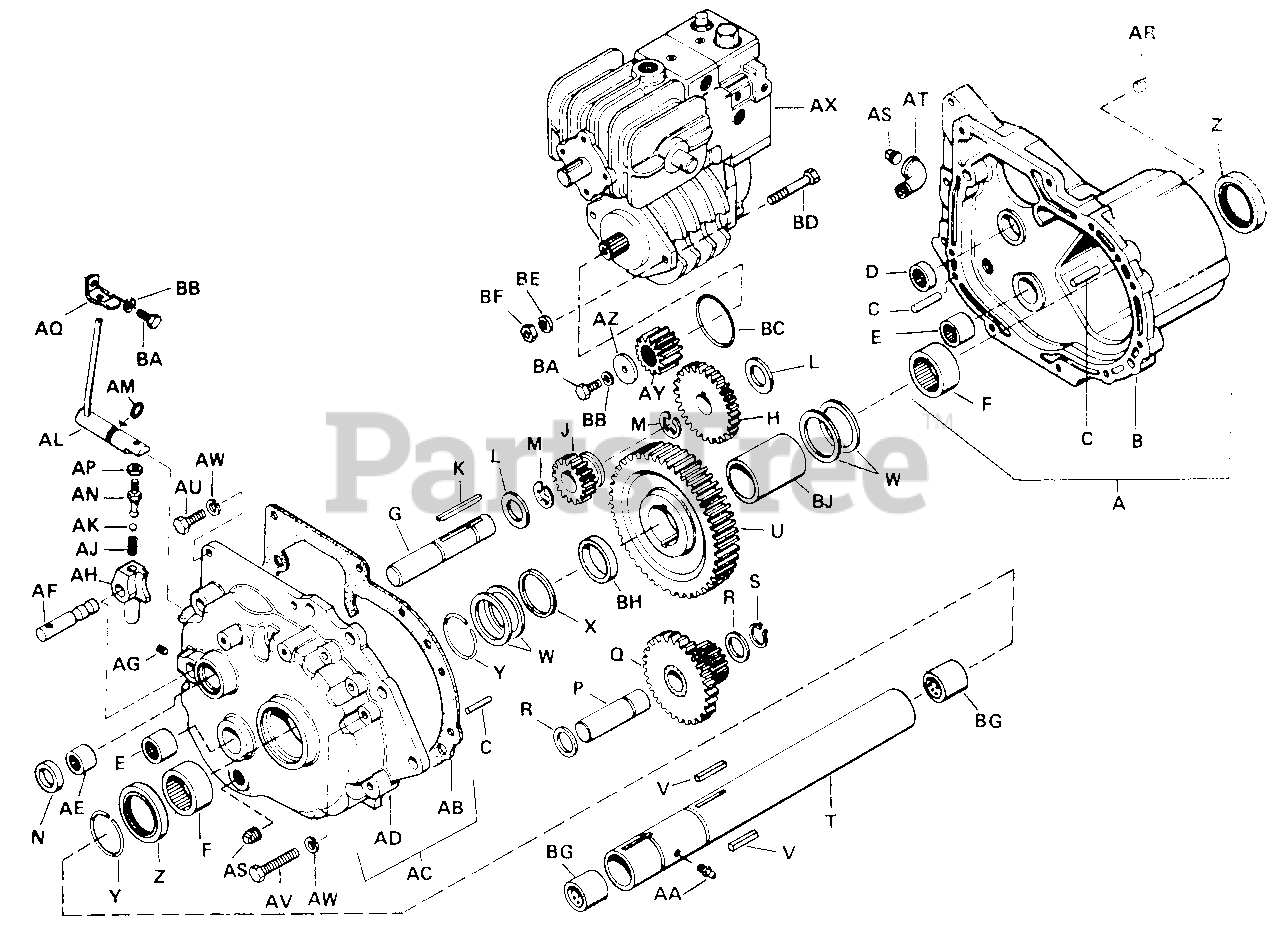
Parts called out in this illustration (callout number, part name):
A	Gear Case Complete (includes B thru F)
B	Gear Case
C	Roll Pin, 3/8 x 1-1/4"
D	Needle Bearing
E	Needle Bearing
F	Needle Bearing
G	Brake Shaft
H	Gear-1st Interm.
J	Sliding Pinion
M	Retainer Ring
P	Shaft, Interm.
Q	Pinion & Gear Assembly
S	Retaining Ring
T	Axle Tube Assembly
U	Drive Gear
AA	Grease Fitting
AB	Gear Case Gasket
AC	Gear Case Cover Sub. Assy. (includes AD, AE, E, F)
AD	Gear Case Cover
AE	Needle Bearing
AF	Shifter Shaft
AG	Cone Pt. Setscrew, Hollow Hd., 5/16"-18 x 1/2"
AH	Shift Fork
AK	Shift Lock Ball
AL	Shift. Shaft Assembly
AP	Hex. Jam Nut, 5/16"-24
AQ	Lift Lever Latch
AR	Pipe Plug, 1/4"
AS	Pipe Plug, 3/8"
AT	Street Elbow, 3/8"
AU	Hex. Capscrew, 5/16-18 x 1"
AV	Hex. Capscrew, 5/16-18 x 2"
AW	Lock Washer, 5/16"
AX	Hydrostatic Pump & Motor Unit
AY	Motor Shaft Pinion
BA	Hex. Capscrew, 5/16-24 x 5/8"
BB	Lock Washer, 5/16"
BD	Hex. Capscrew, 7/16-14 x 4"
BE	Lock Washer, 7/16"
BF	Hex. Nut, Full, 7/16"-14
BH	Spacer (R.H.Side)
BJ	Spacer (L.H.Side)
